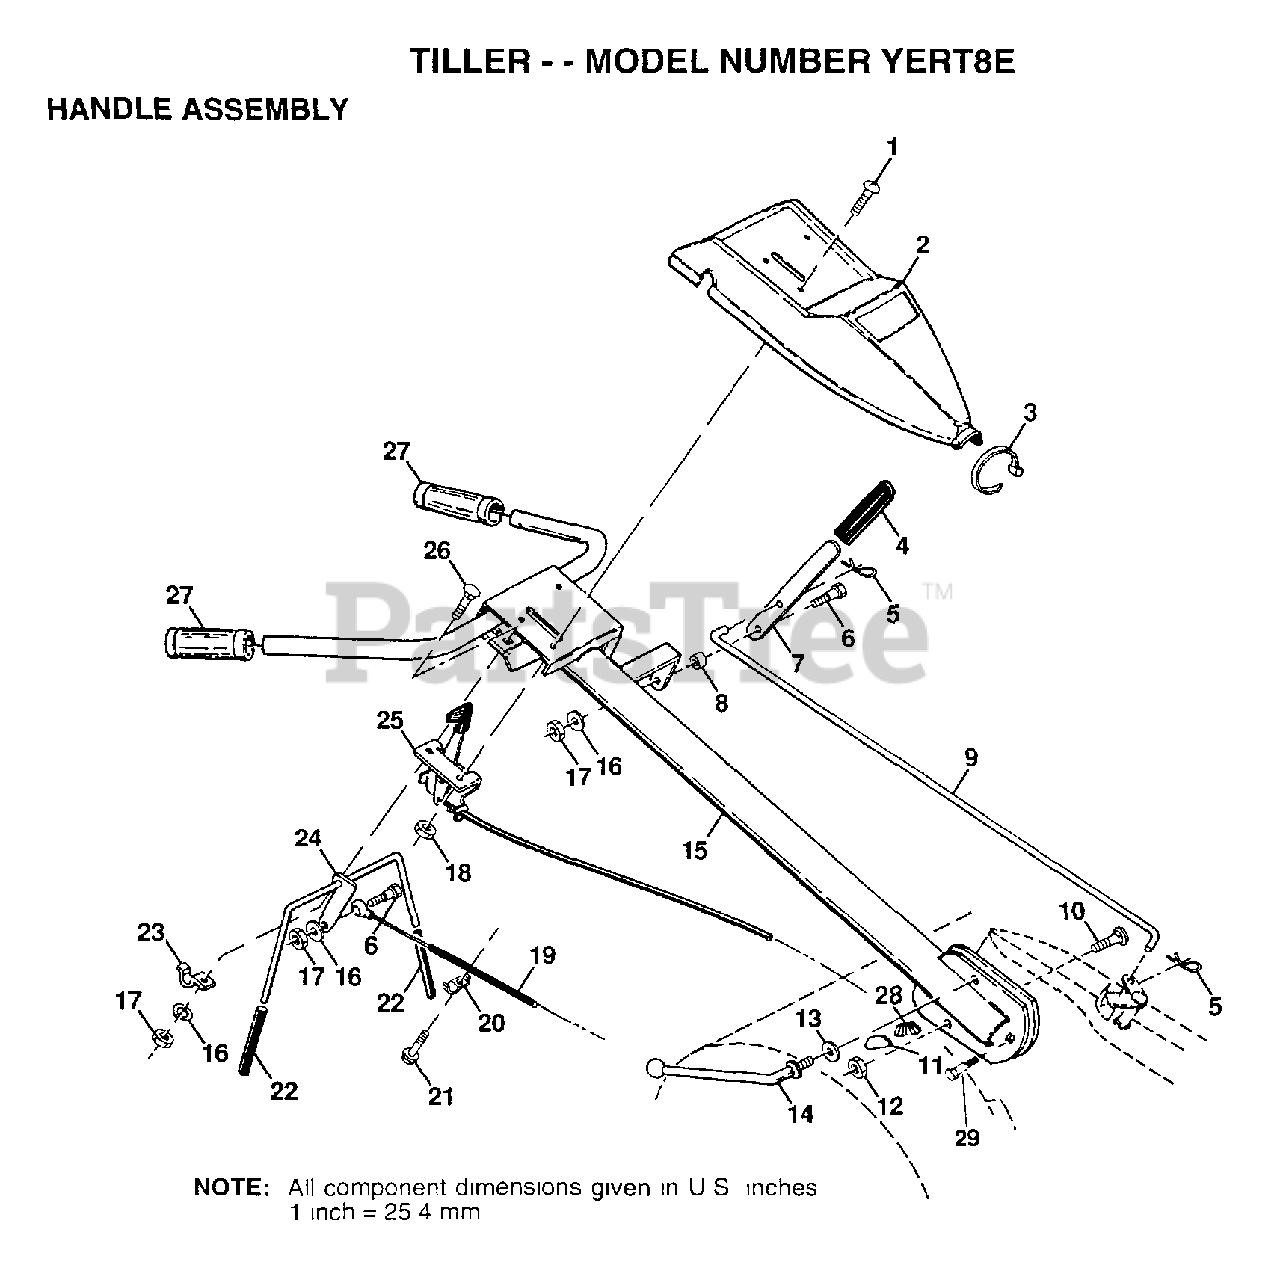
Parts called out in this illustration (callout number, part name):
1	SCREW.PNHD.10-24
2	"PANEL,CONT TI"
3	TIE CABLE CRT
4	GRIP T
5	RETAINER M
6	SHOULDER BOLT ST
7	SHIFT HANDLE CRT
8	GROMMET CRT
9	ROD.SHIFT
10	BOLT D
11	LOCK CRT
12	LOCKNUT
13	WASHER CRT
14	LEVER LOCK CRT
16	LOCKWASHER
19	CABLE-CLUTCH CRT
20	CONDIUT CLIP T
22	GRIP BAR CRT
24	"ASSY CONTROL, BAR"
25	CONTROL.THROTTLE
26	BOLT
28	LOCK.HANDLE
29	BOLT PIVOT
